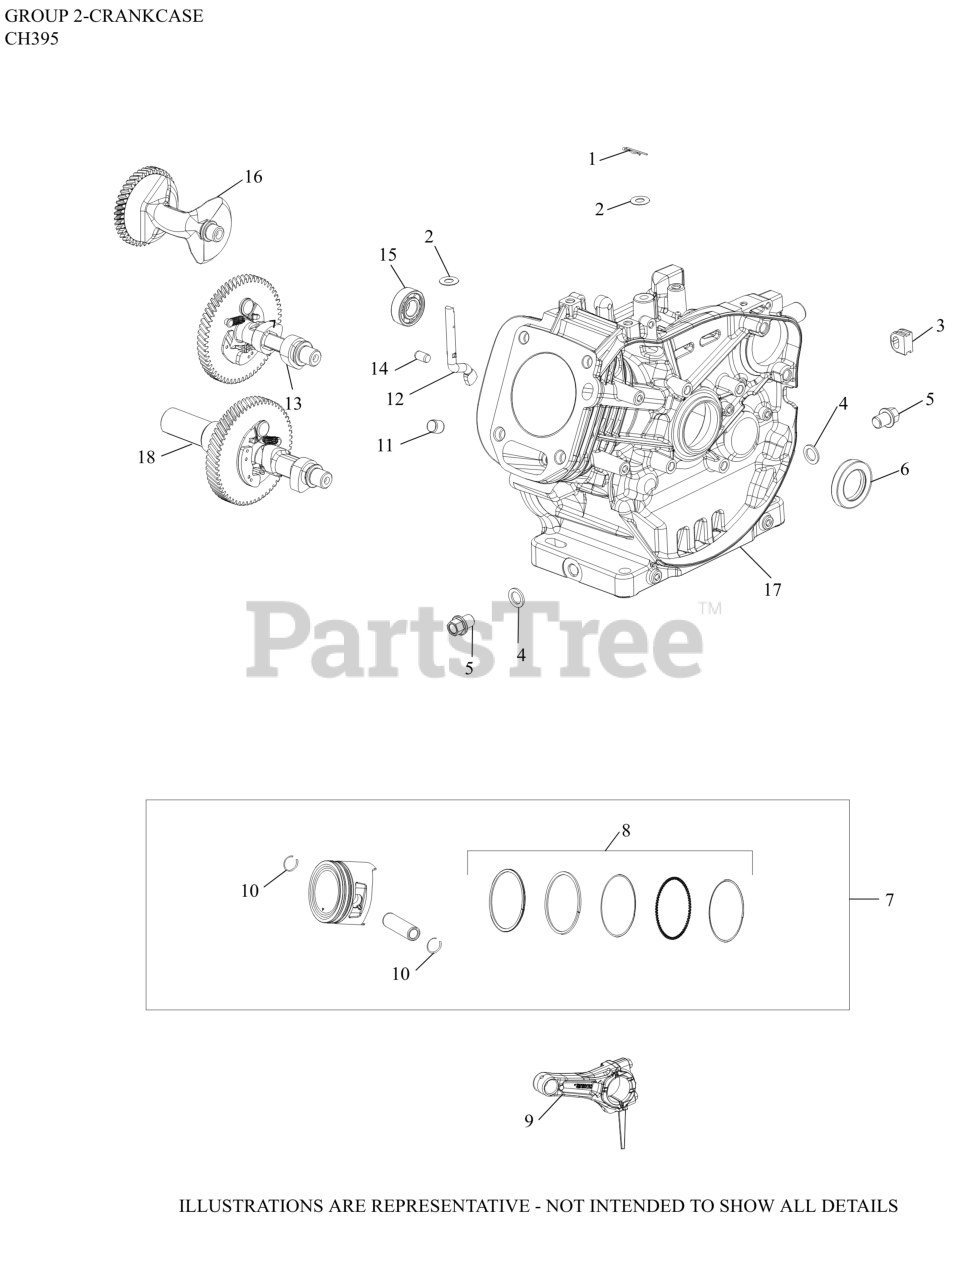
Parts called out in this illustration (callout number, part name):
1	CLIP, GOVERNOR SHAFT
2	WASHER, FLAT
3	GROMMET, CRANKCASE
4	WASHER, DRAIN PLUG
5	KIT, DRAIN PLUG
6	SEAL, RADIAL SHAFT
7	KIT, PISTON - (#1787406S)
7	KIT, PISTON-USE 17 874 14-S
7	KIT, PISTON AND RINGS
8	RING SET- USE 17 874 06-S
8	RING, SET PISTION (std)
9	ROD, CONNECTING ASSEMBLY
10	RETAINER, PISTON PIN
11	PIN, DOWEL CYLINDER HEAD
12	SHAFT, GOVERNOR CROSS
13	CAMSHAFT ASSEMBLY
14	PIN, DOWEL
16	SHAFT, BALANCE
17	CRANKCASE
